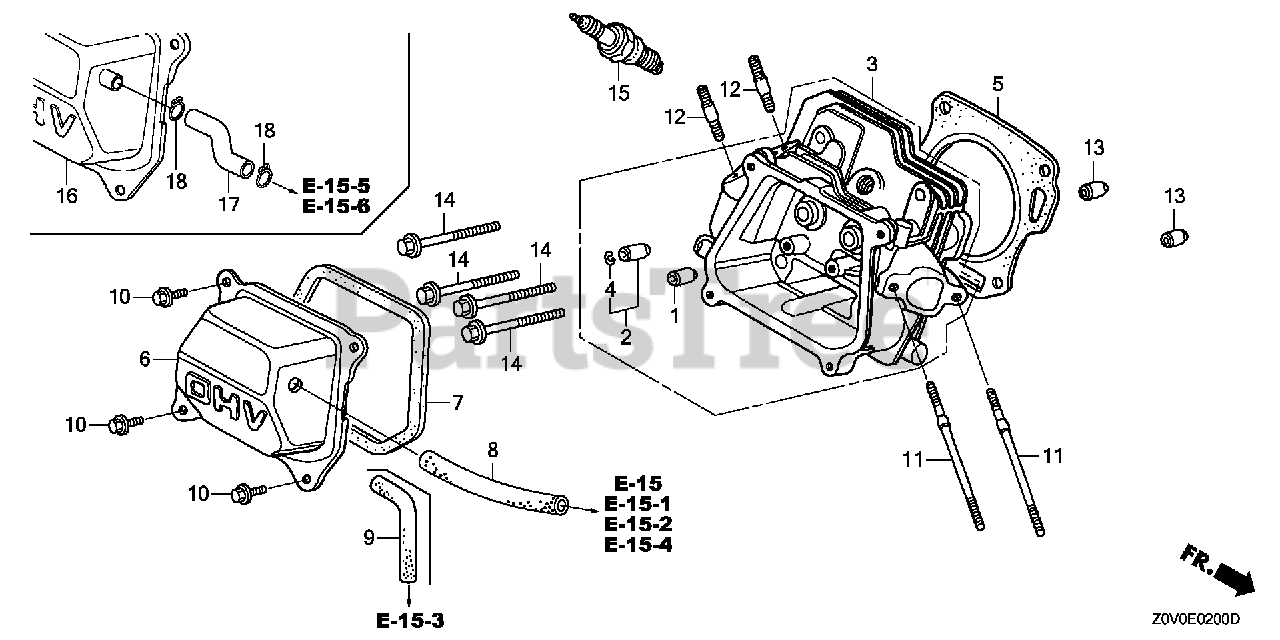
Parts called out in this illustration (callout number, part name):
1	GUIDE, VALVE (OVER SIZE) Use from Engine SN 6324986.
2	GUIDE, EX. VALVE (OS)
3	CYLINDER HEAD
4	CLIP, VALVE GUIDE Use from Engine SN 1231803.
5	GASKET, CYLINDER HEAD (NIPPON LEAKLESS)
6	COVER, HEAD
7	GASKET, CYLINDER HEAD COVER
7	GASKET, HEAD COVER
8	TUBE, BREATHER
10	BOLT, FLANGE (6X12) (CT200)
11	BOLT, STUD (6X109)
12	BOLT, STUD (8X32)
13	PIN A, DOWEL (10X16)
14	BOLT, FLANGE (8X60)
15	SPARK PLUG (BPR5ES) (NGK)
15	SPARK PLUG (BPR6ES) (NGK)
